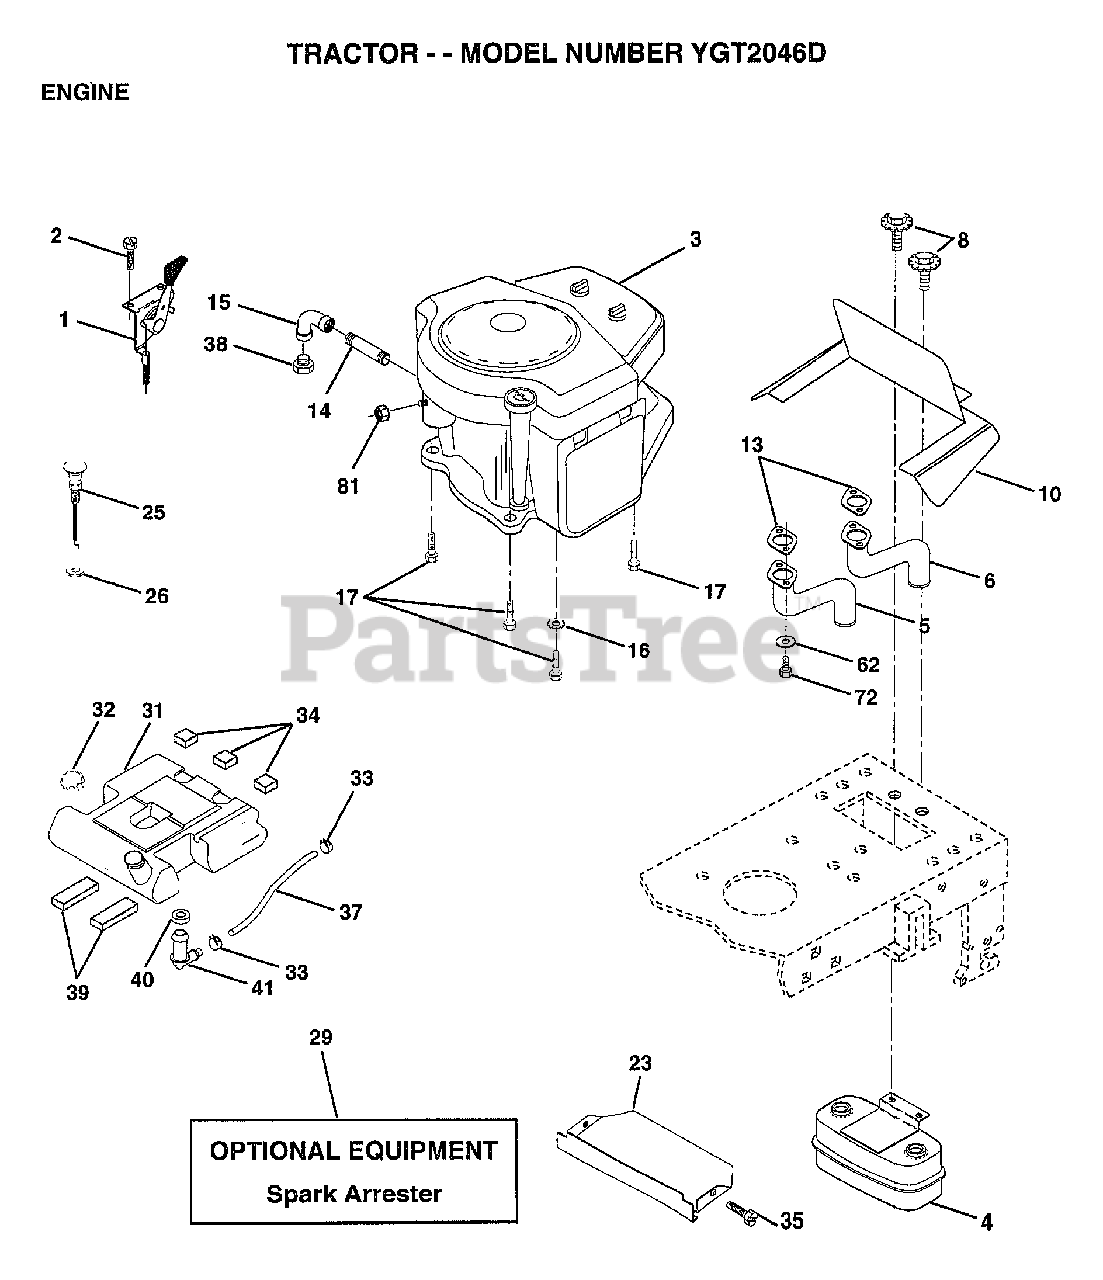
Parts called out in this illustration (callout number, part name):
2	SCREW LT
4	MUFFLER.TW.LOTONE
5	TUBE MANIFOLD LH
6	TUBE MANIFOLD RH
7	"CLIP,INSULATOR"
8	BOLT.5/16-18.UNC
10	SHIELD.BROWNING
14	PIPE NIPPLE LT
15	ELBOW
16	LOCKWASHER
17	SCREW LT
23	SHIELD.BRN/DBR.GD
25	"CONTROL.CHOKE.51"""
26	"NUT,KEPS 3/8-24IM"
31	TANK FUEL REAR
32	CAP ASM FUEL
33	HOSE CLAMP
34	PAD-SPACER LT
35	SCREW
37	FUEL LINE T
39	PAD IDLER TI
40	BUSHING OUTLET T
41	STEM.TANK.FUEL
62	LOCKWASHER
72	SCREW
81	NUT
